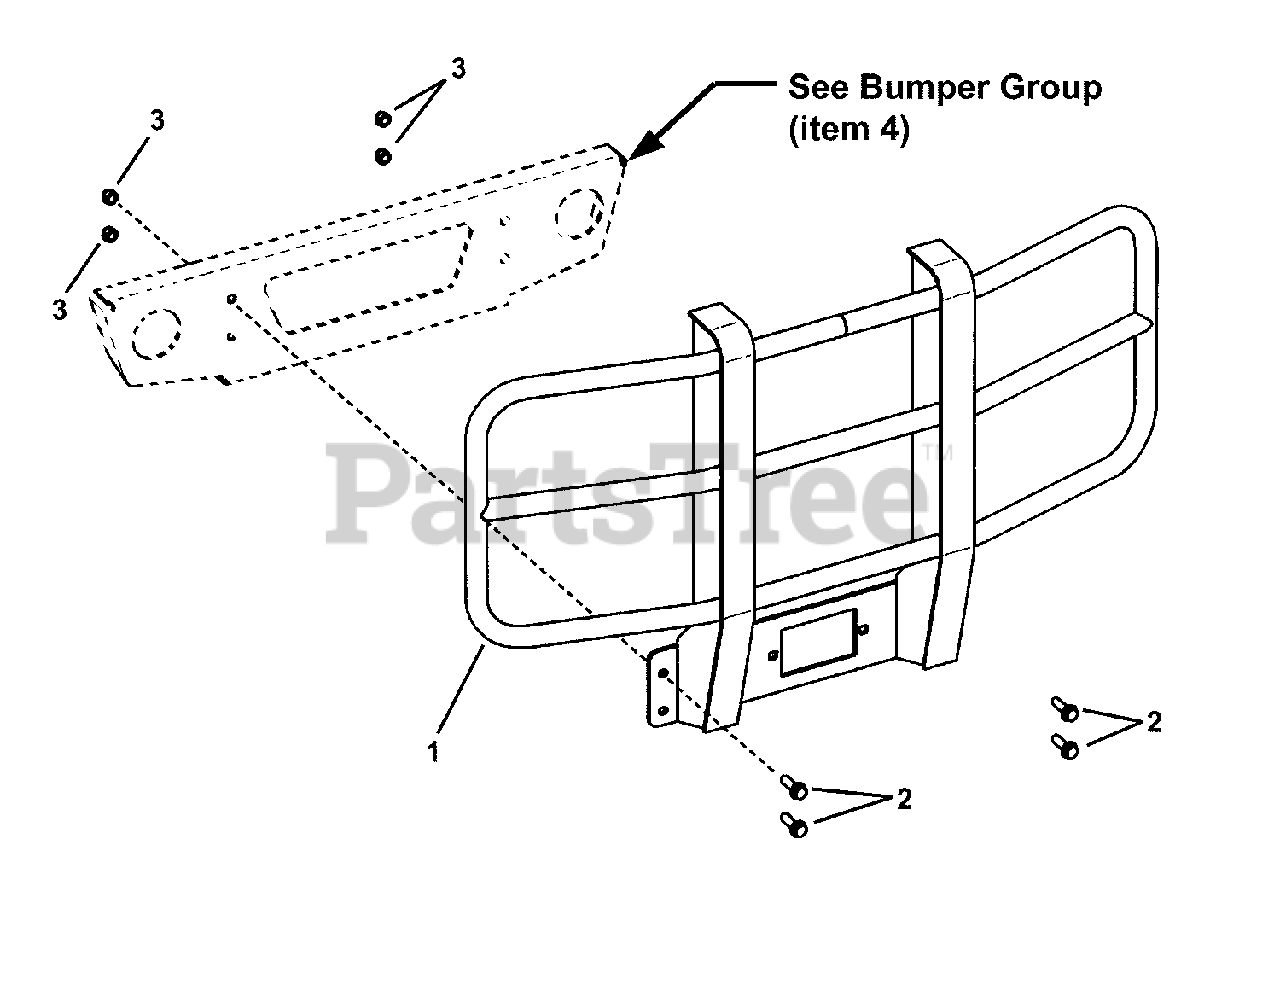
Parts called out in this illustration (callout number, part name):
1	BRUSH GUARD (weldment)
2	BOLT, 3/8-16 x 1-1/4" Hex Flange Lock
3	NUT, 3/8-16 Hex Nyloc
